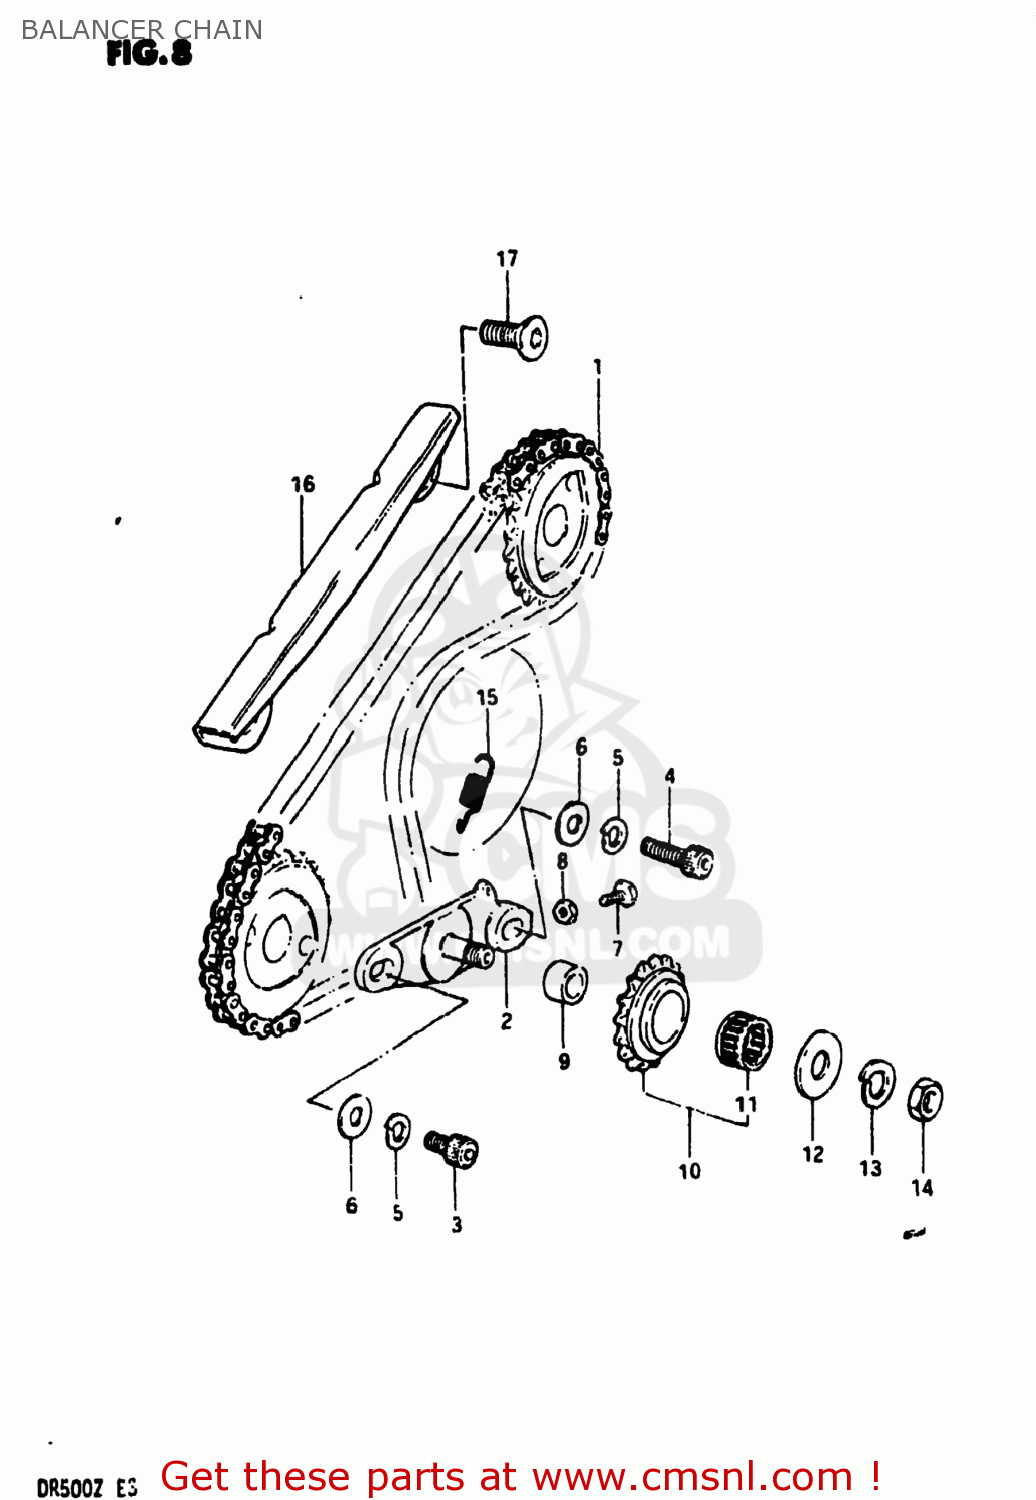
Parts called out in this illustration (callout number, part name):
1	GOVERNOR ASSEMBLY,EXHAUST
2	BRACKET,BALANCER CHAIN TENSIONER
3	BOLT(8X22)
4	BOLT
5	LOCK WASHER
6	WASHER
7	BOLT 5X20
8	NUT
9	SPACER,TENSIONER SPROCKET
10	ROD,EXHAUST VALVE
11	BEARING(17X23X12)
12	WASHER
13	WASHER,LOCK 12
14	NUT
15	SPRING
16	GUIDE,BALANCER CHAIN
17	SCREW
